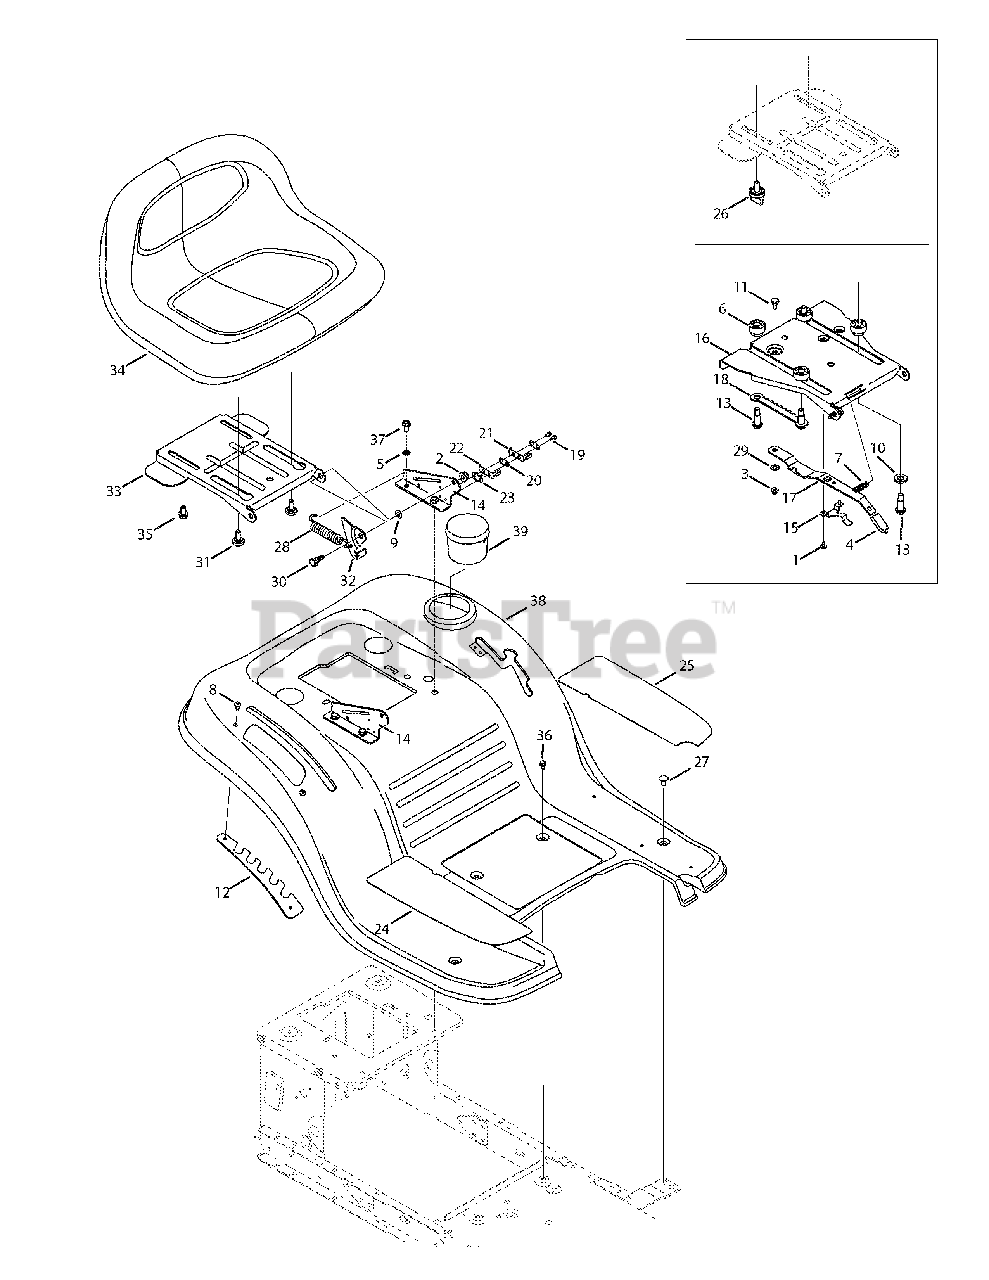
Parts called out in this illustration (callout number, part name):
1	Screw, #10-16, .375
2	Nut, Flange Lock, 5/16-18, GrF
3	Nut, Flange Lock, 1/4-20
4	Seat Adjuster Grip
5	Lock Washer, 5/16
6	Spacer
7	Compression Spring, .41 x 1.5
8	Screw, 1/4-20 x .500
9	Wash, Bell, .340 x .872 x .060
10	Wash, Flat, .531x 1.062 x.134
11	Screw, Shlder, .340 x .285,1/4-20
13	Screw, Shlder, .50 x .925, 3/8-16
15	Seat Stop
18	Seat Adjustment Selector
19	Screw, #8-18 x .50
20	Plate, Insulator
21	Spring Switch, Outer
22	Spring Switch, Inner
23	Plate, Insulator Boss
24	Foot Pad, Abrasive, RH
25	Foot Pad, Abrasive, LH
26	Knob, 3/8-16, .875
27	Carriage Screw, 1/4-20 x .62
28	Spring, Exten., .84 Dia x 4.6 Lg.
29	Wash, Flat, .344 x .62 x .033
30	Scr., Shlder, .437 x .268, 5/16-18
31	Screw, Shlder, .625 x .175, 3/8-16
32	Lift Bracket, Seat
34	Seat, Low, Black
35	Screw, 3/8-16, .875
36	Screw, 1/4-20, 0.500
37	Screw, 5/16-18, 0.750
39	Cup Holder
40	Flat Washer, .406 x .875 x .059
